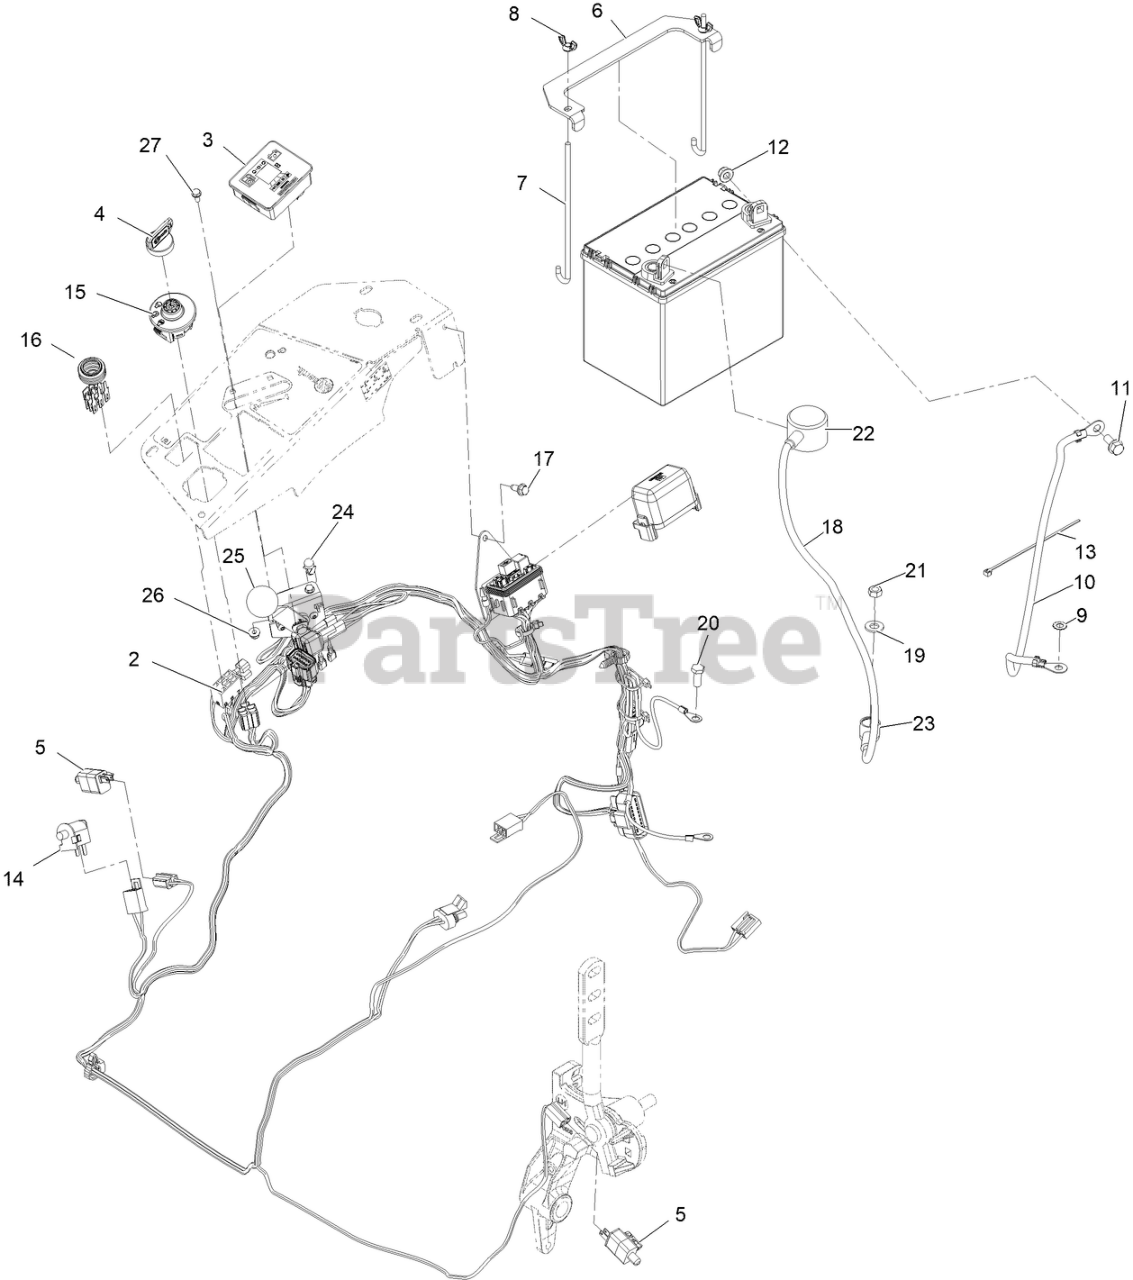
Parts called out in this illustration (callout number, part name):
2	HARNESS-MAIN
3	FUEL-HOUR METER ASM
4	KEYS-IGNITION (SPARE PAIR
4	KEY-IGNITION
6	STRAP-TIE DOWN, BATTERY
7	BOLT-HOLDDOWN
8	WINGNUT
9	WASHER-LOCK
10	CABLE-BATTERY, NEGATIVE
11	SCREW-HHF
12	NUT-HF, NI
13	TIE-CABLE
14	SWITCH-BAIL
15	SWITCH-IGNITION
16	SWITCH, PTO 10A
17	SCREW-HWH
18	CABLE-BATTERY, POSITIVE
19	WASHER-FLAT
20	SCREW-HH
21	NUT-HEX
22	INSULATOR-BATTERY
23	INSULATOR-SOLENOID
24	INDICATOR-LED, RED
25	THROTTLE CONTROLLER-ETC
27	SCREW-HWH
